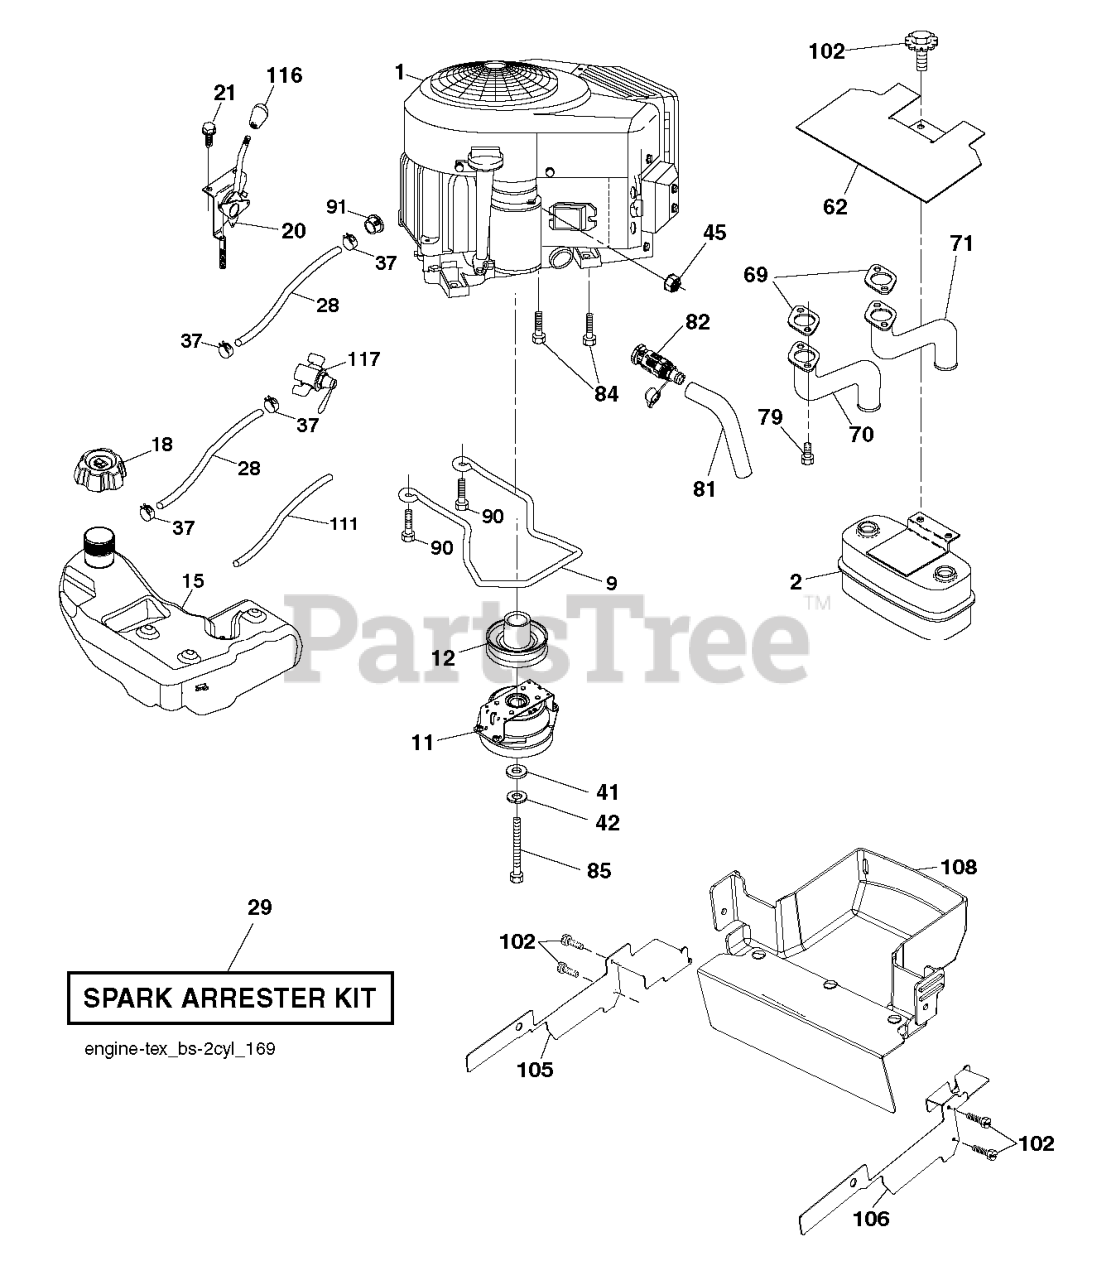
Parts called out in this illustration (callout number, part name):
2	MUFFLER.ASM.TWN.EXTNDED.DFLCTR
9	KEEPER.BELT.ENG.4.25"2.BLT.431
11	CLUTCH.OGURA.5.0PD.GT1.5A-EH01
12	PULLEY ENGINE
18	CAP.ASSY.FUEL.3".N-EPA.GRY.498
20	CONTROL.THROTTLE.PRO.
21	SCREW.#10 X 0.750.BOS
28	HOSE 1/4" LOW PERMEATION FUEL
29	KIT.SPARK ARRESTOR 794945 B&S
37	HOSE CLAMP
42	WASHER 7/16 LOCK
45	NUT
62	SHIELD.HEAT.MUFFLER
69	GASKET.MUFFLER
70	EXHAUST.TUBE.LH.BS/TWIN
71	EXHAUST.TUBE.RH.B&S.TWIN.INTEK
79	SCREW.SOCKET.HEAD.5/16-18
81	TUBE, DRAIN OIL ASM.
82	VALUE.OIL.DRAIN
84	SCREW.3/8-16
85	BOLT.HEX.7/16-20X3.GR5.YELLOW
90	SCREW 3/8-16X1
91	BUSHING.1.375OD
102	SCREW
105	SHIELD 48 CLEARCUT EURO TRACTO
106	SHIELD 48 CLEARCUT EURO TRACTO
108	COVER 48 CLEARCUT EURO TRACTOR
111	RP PURGE LINE
116	KNOB - SHIFT
117	VALVE FUEL RESERVE
